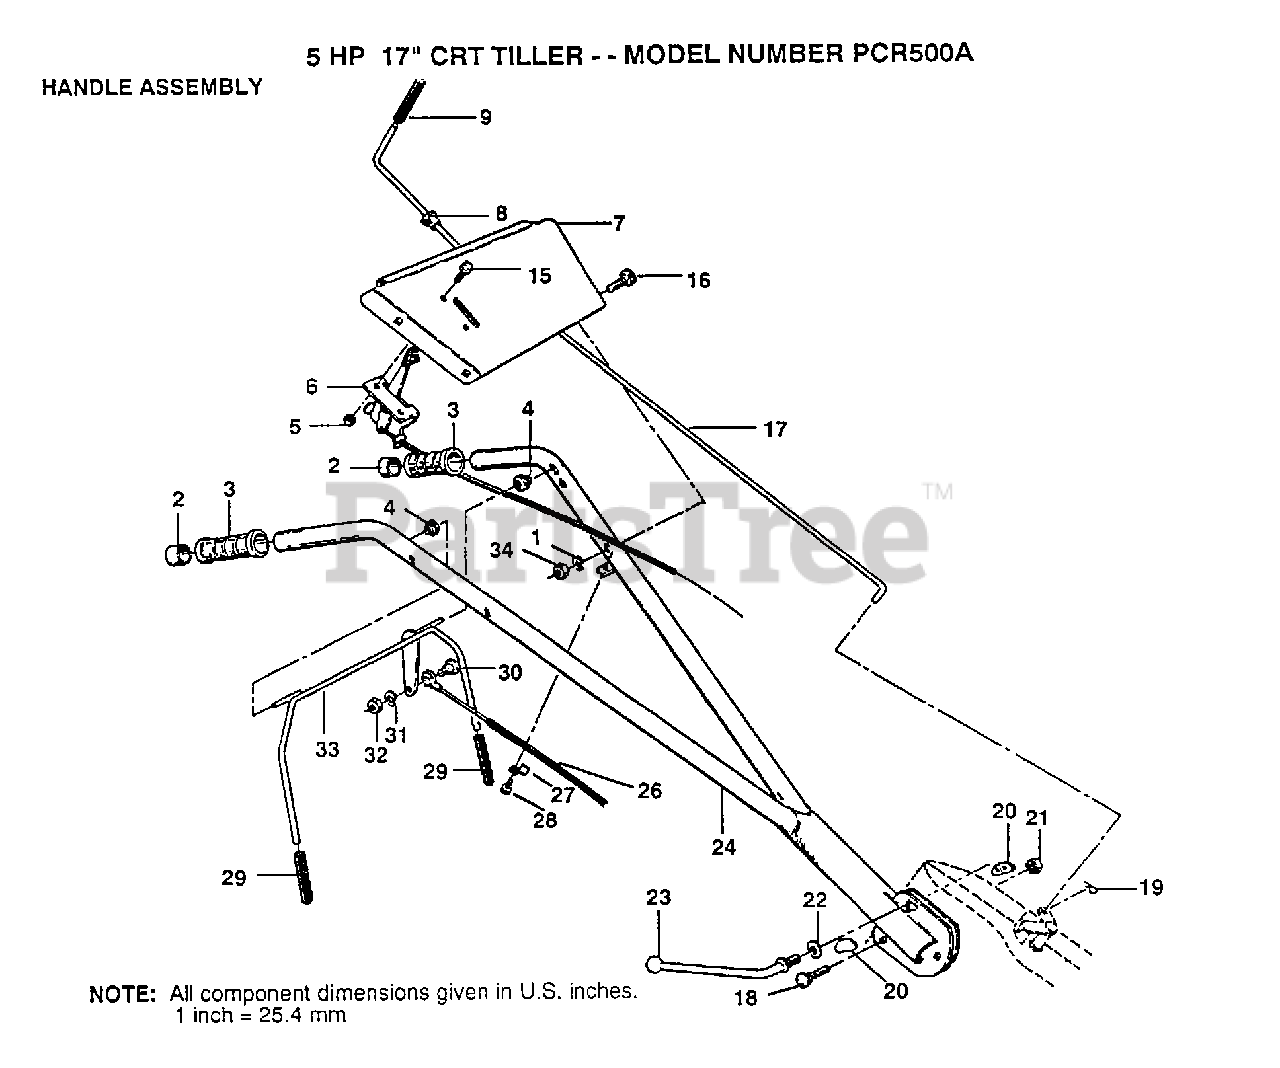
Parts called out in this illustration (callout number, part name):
1	LOCKWASHER
2	CAP CRT
6	"CONT,THROTTLE"
8	BUSHING
9	GRIP TI
15	SCREW
16	BOLT CARRIAGE CRT
17	ROD SHIFT CRT
18	BOLT D
19	RETAINER M
20	LOCK CRT
22	WASHER CRT
23	LEVER LOCK CRT
26	CABLE.CLUTCH.CRT
27	CONDIUT CLIP T
29	GRIP BAR CRT
30	SHOULDER BOLT ST
31	LOCKWASHER
33	HANDLE BAR CRT
